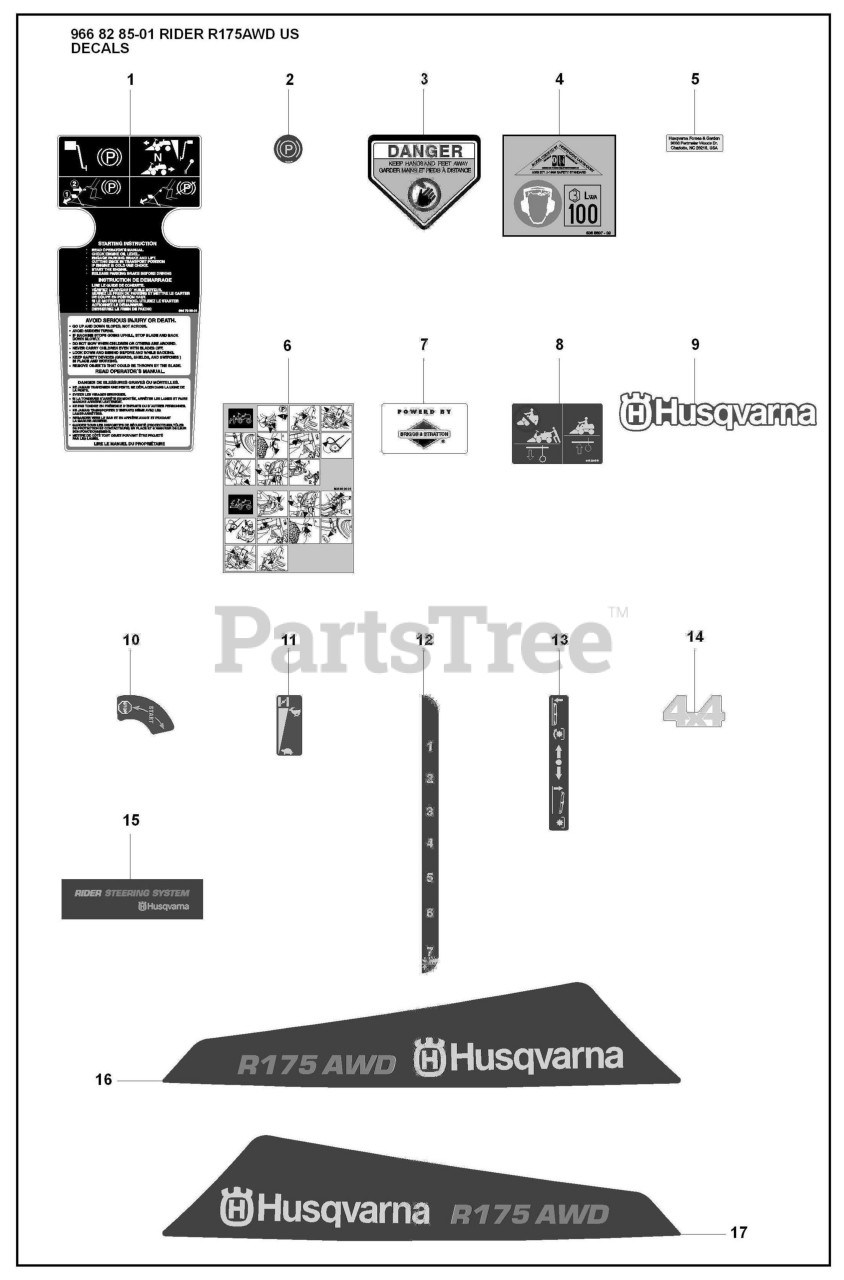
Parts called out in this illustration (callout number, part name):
4	REPL BY 506 88 07-03
16	LABEL
17	LABEL
